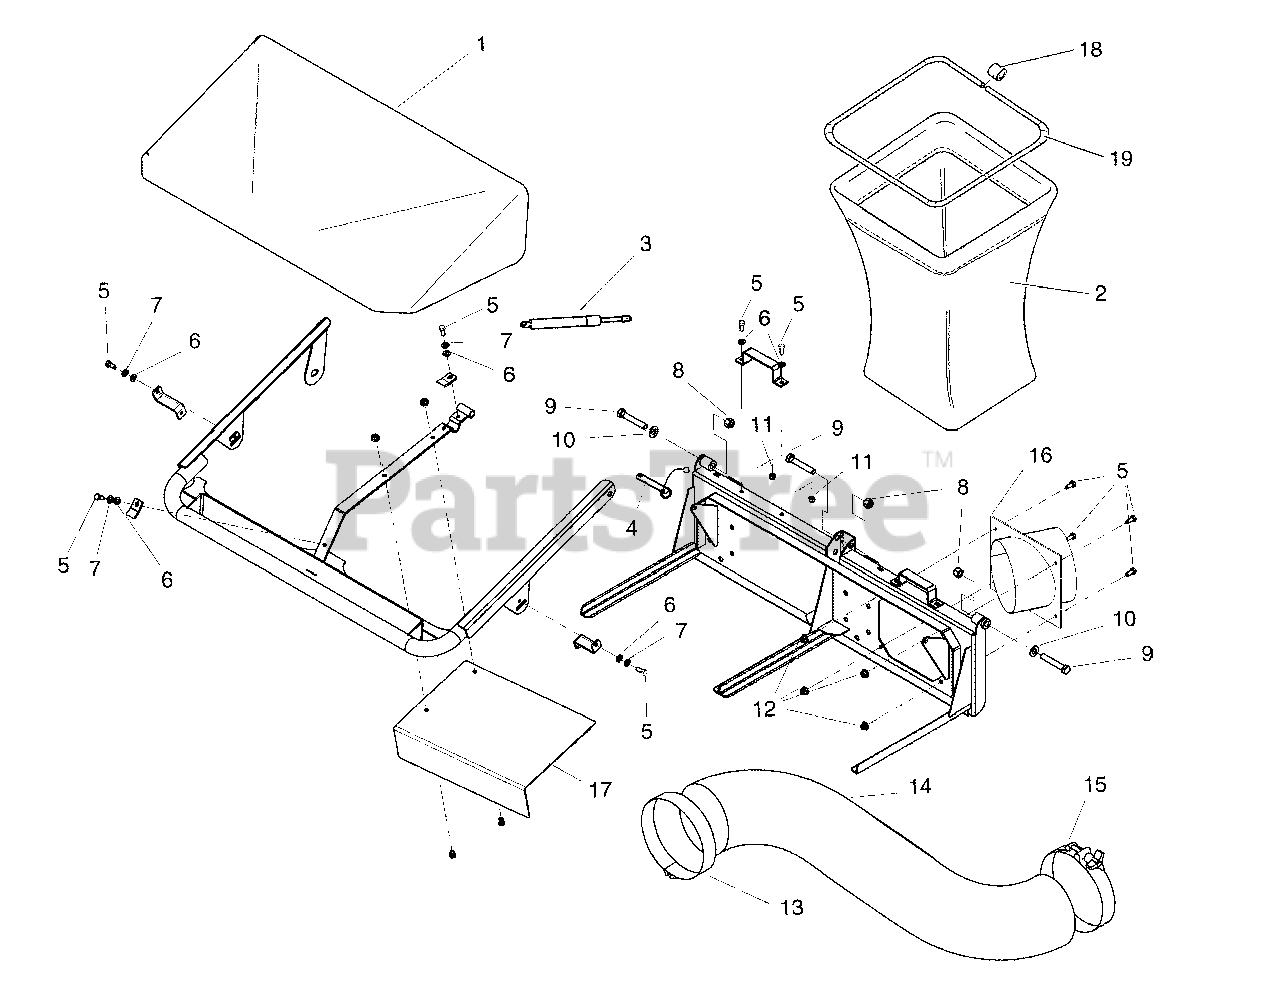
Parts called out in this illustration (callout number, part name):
1	2 BAG AIR DOME
2	CATCHER BAG W/ HANDLE
3	GAS CYLINDER
4	DETENT PIN W/ LANYARD
5	BOLT, 5/16-18 X 3/4 GD5
6	WASHER, 5/16" SAE
7	WASHER, 5/16" LOCK
8	NUT, 1/2-13 HEX NYLON LOCK
9	BOLT, 1/2-20 X 3" GD5
10	WASHER, 1/2 SAE
11	NUT 5/16-18 HEX NYLON LOCK
12	NUT 5/16-18 HEX NYLOCK FLANGE
13	HOSE CLAMP
14	HOSE, FLEXIBLE, 7" DIA. X 58"
15	HOSE CLAMP
16	WELD, INLET BLOWER
17	BAFFLE
18	BAG FRAME CONNECTOR, PLASTIC
19	BAG FRAME
